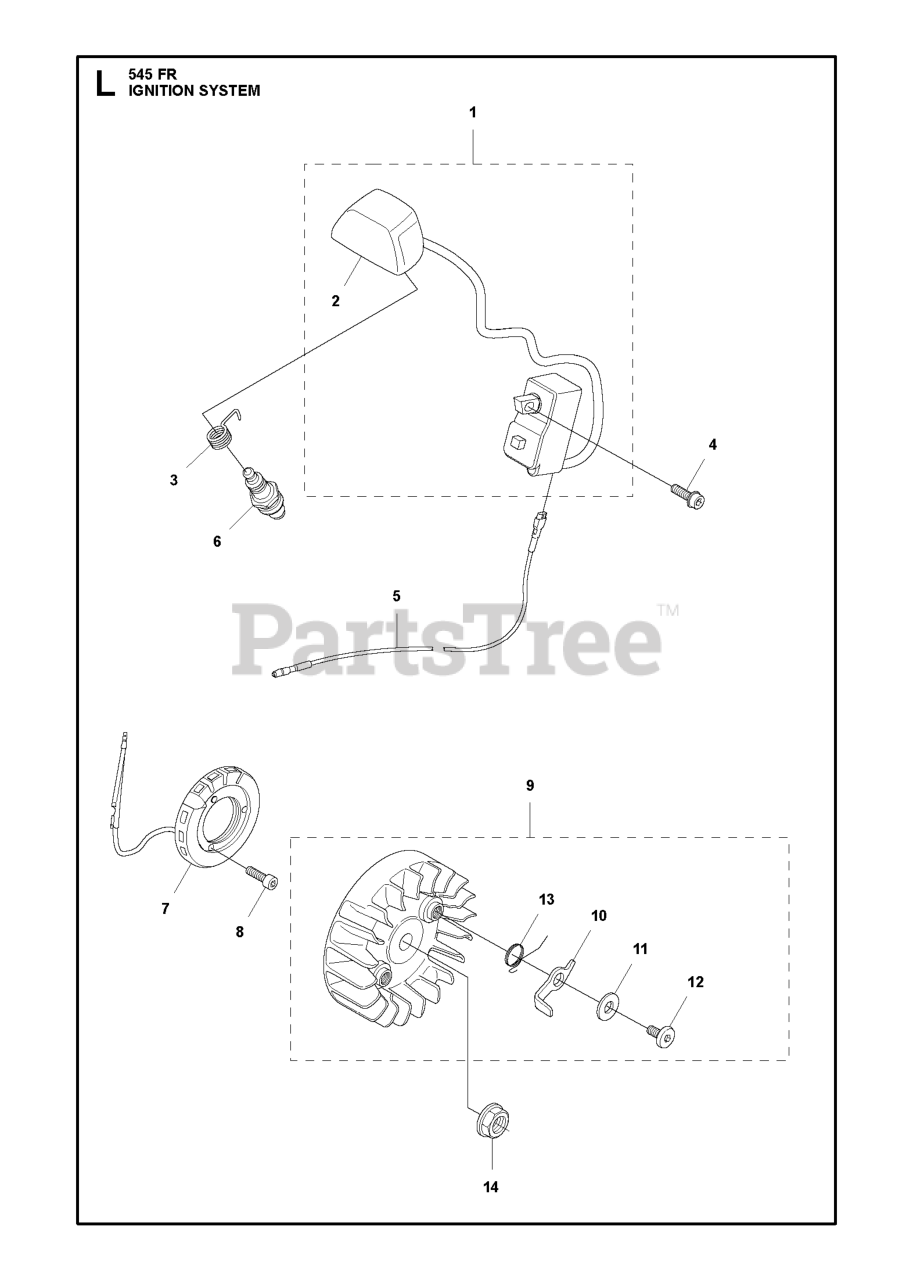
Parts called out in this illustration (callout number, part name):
1	IGNITION MODULE
2	SPARK PLUG CAP
3	CONTACT SPRING
4	SCREW IHSCFM
5	SHORT CIRCUIT CABLE
6	CMR6H SPARK PLUG NGK
10	STARTER PAWL
13	SPRING
14	NUT W/ WASHER
